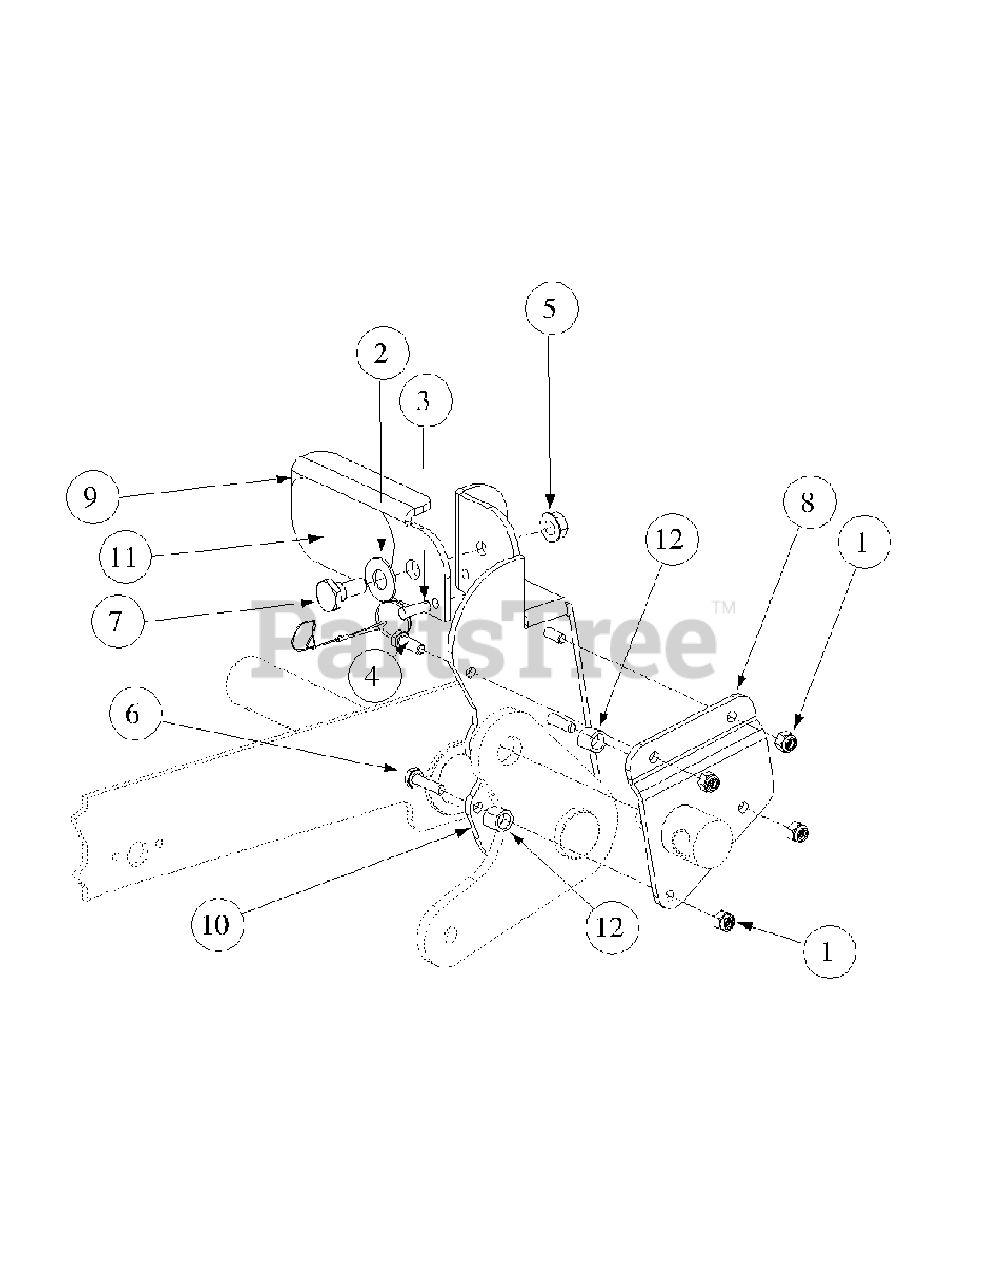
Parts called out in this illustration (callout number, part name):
1	Lock Nut, Nylon Insert, 1/4-20
2	Washer, 1/2 x 1 Shim
3	Detent Pin w/Lanyard, 1/4"
4	Hex Cap Screw, 1/4-20, .75
5	Hex Nut, Flange Lock 3/8-16
6	Hex Cap Screw, 1/4-20, 1.00
7	Shoulder Screw, .50x.27 Lg., 3/8-16
8	Foot Lift Backup Pedal
9	Deck Foot Pedal Lift
10	Deck Foot Pedal Lift Holder
11	Deck Foot Lift Pad
12	Turnbuckle Sleeve
